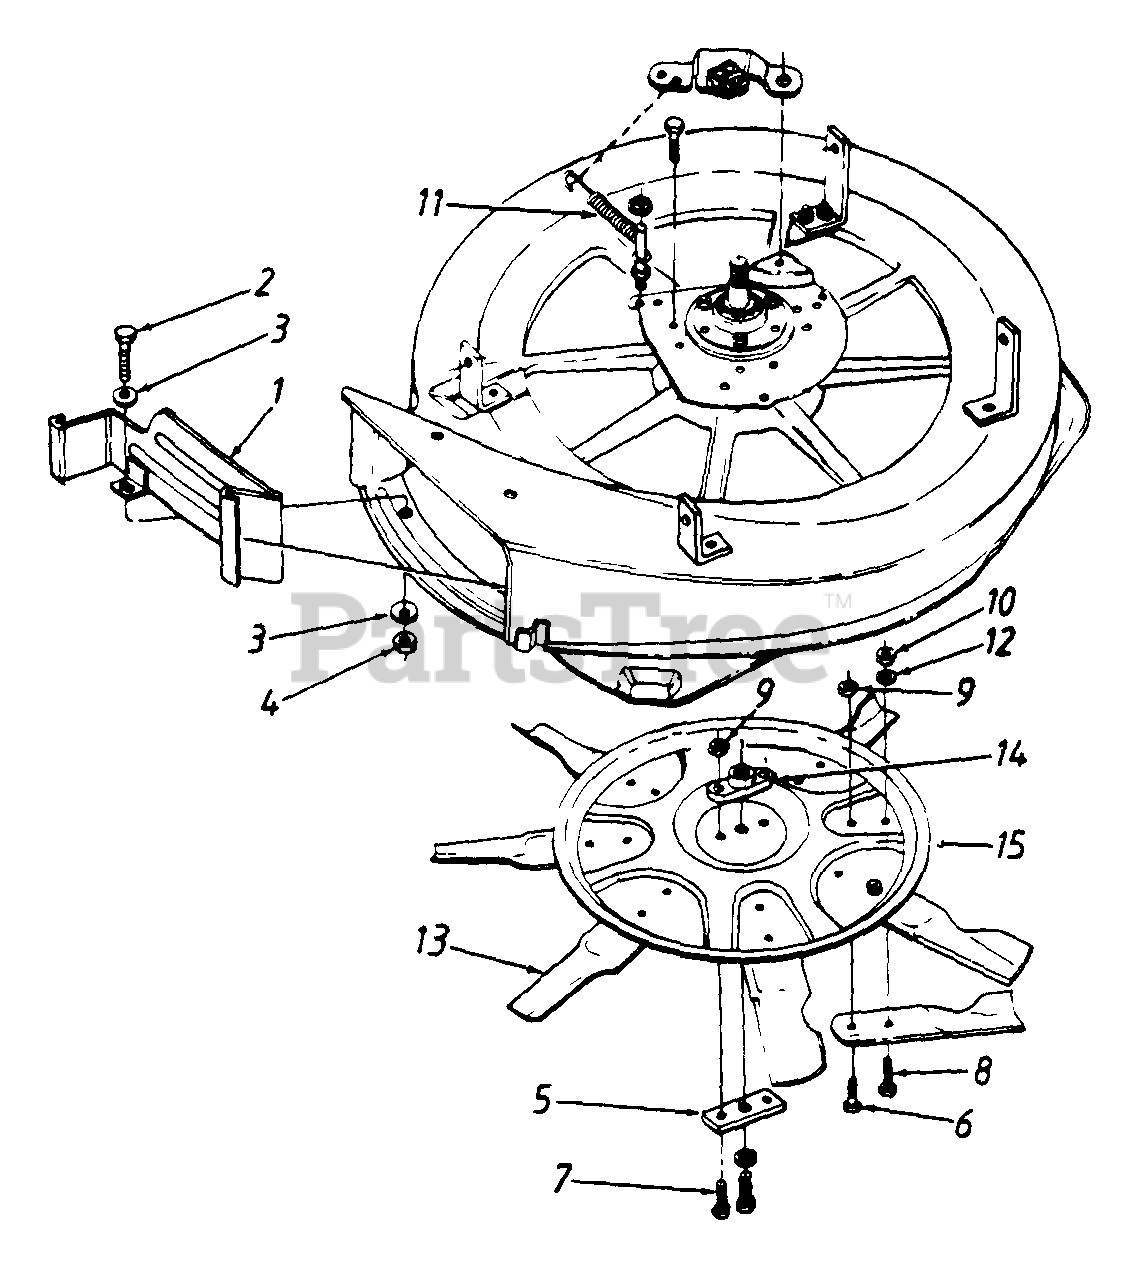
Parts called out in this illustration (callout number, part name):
1	Mulching Baffle Ass'y.
2	Hex Bolt 5/16-18 x 5"
3	Bell-Wash..325" I.D.
4	Hex L-Nut 5/16-18 Thd.
7	Hex Bolt 5/16-24 x 1.25" Lg (Gr. 5)
8	Hex Bolt 3/8-24 x .88" Lg.
9	Hex L-Nut 5/16-24 Thd
10	Hex L-Nut 3/8-24 Thd. (Gr 5)
11	Extension Spring 3.2" Lg.
12	Fl-Wash..406" 1.D. x .75"
13	30" Mulching Blade Tip
14	Blade Adapter
15	30" Mulching Blade Disc
